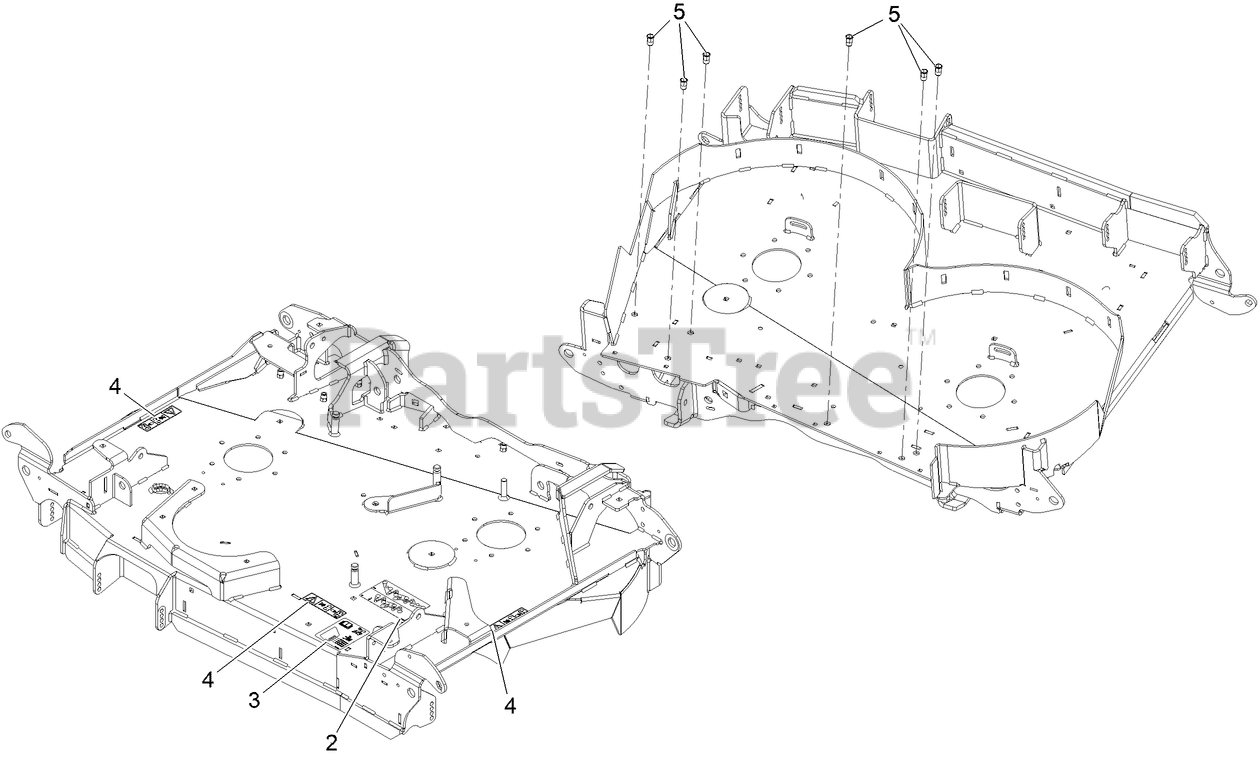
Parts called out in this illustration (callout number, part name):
2	DECAL-DECK BELT ROUTING
3	DECAL-ROLLER, ANTI-SCALP
4	DECAL-COVER, MISSING
5	NUT-CLINCH,HEX
